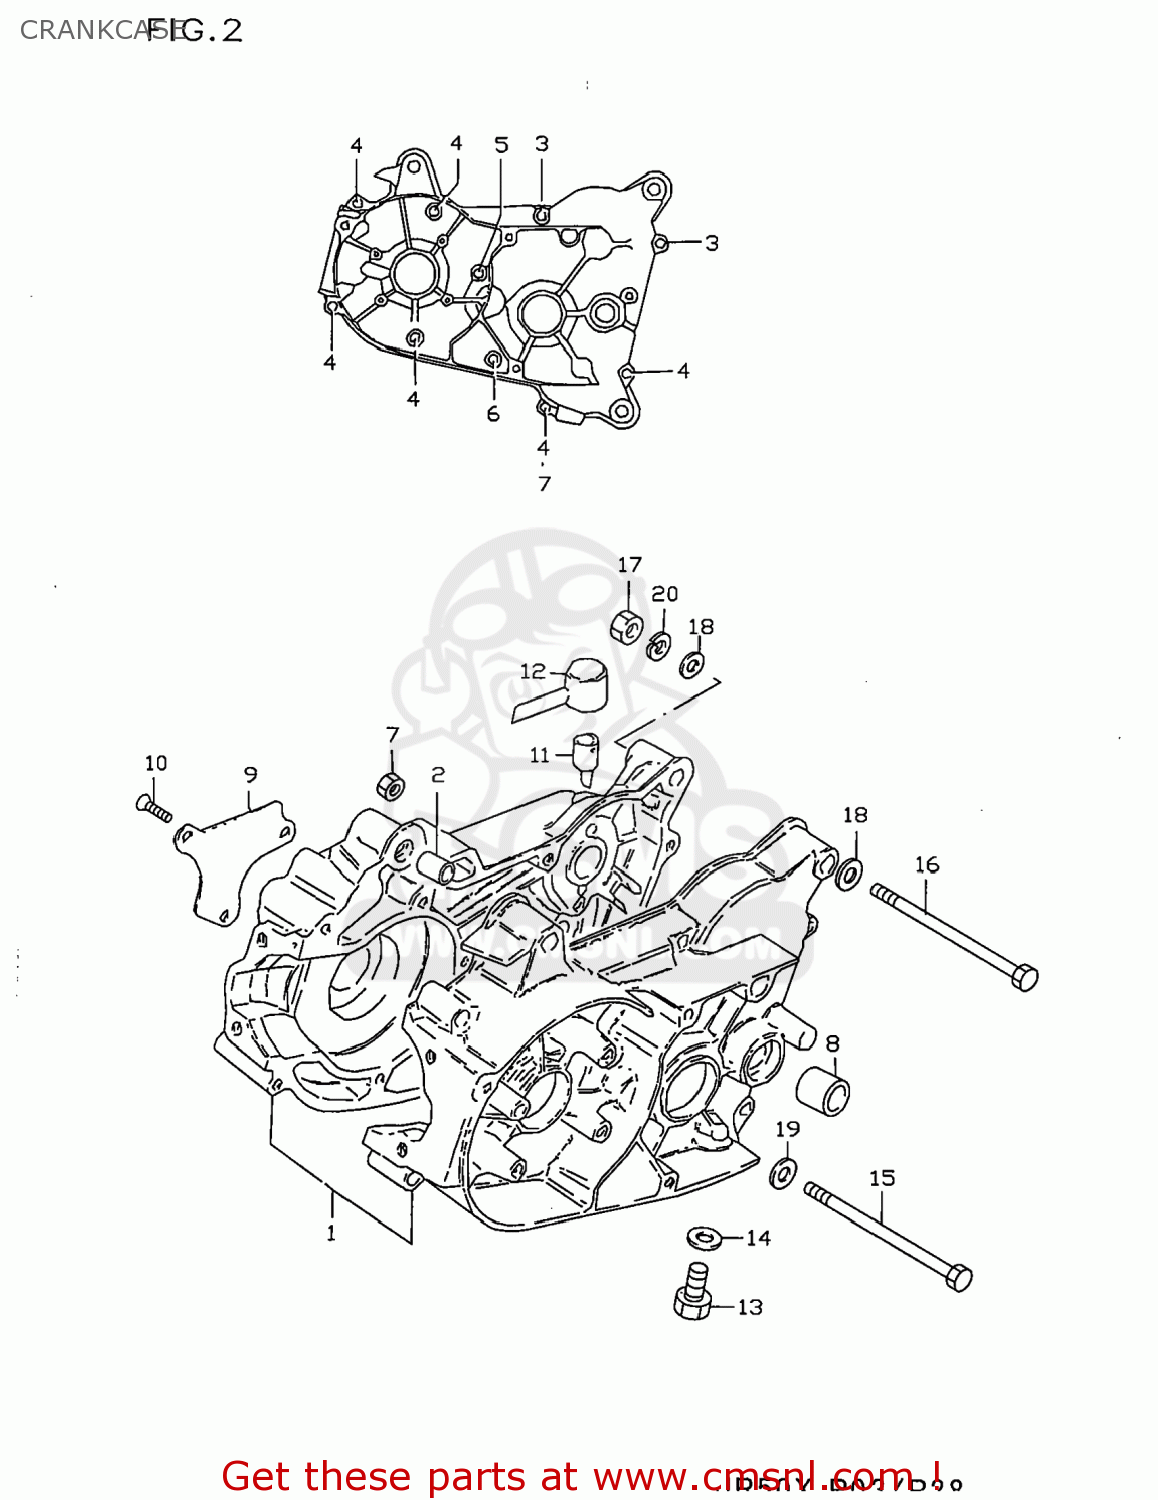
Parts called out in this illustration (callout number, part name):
1	CRANKCASE SET
2	PIN
3	SCREW 6X30
4	SCREW
5	SCREW
6	SCREW
7	NUT 6MM
8	BUSH
9	PLATE,OIL RESERVOIR
10	SCREW,UPPER
11	PLUG,T/M BREATHER
12	GASKET (NAS)
13	PLUG
14	GASKET(10X14X3.6) (NAS)
15	BOLT
16	BOLT
17	NUT
18	WASHER
19	WASHER(8.5X22X3.2)
20	LOCK WASHER
